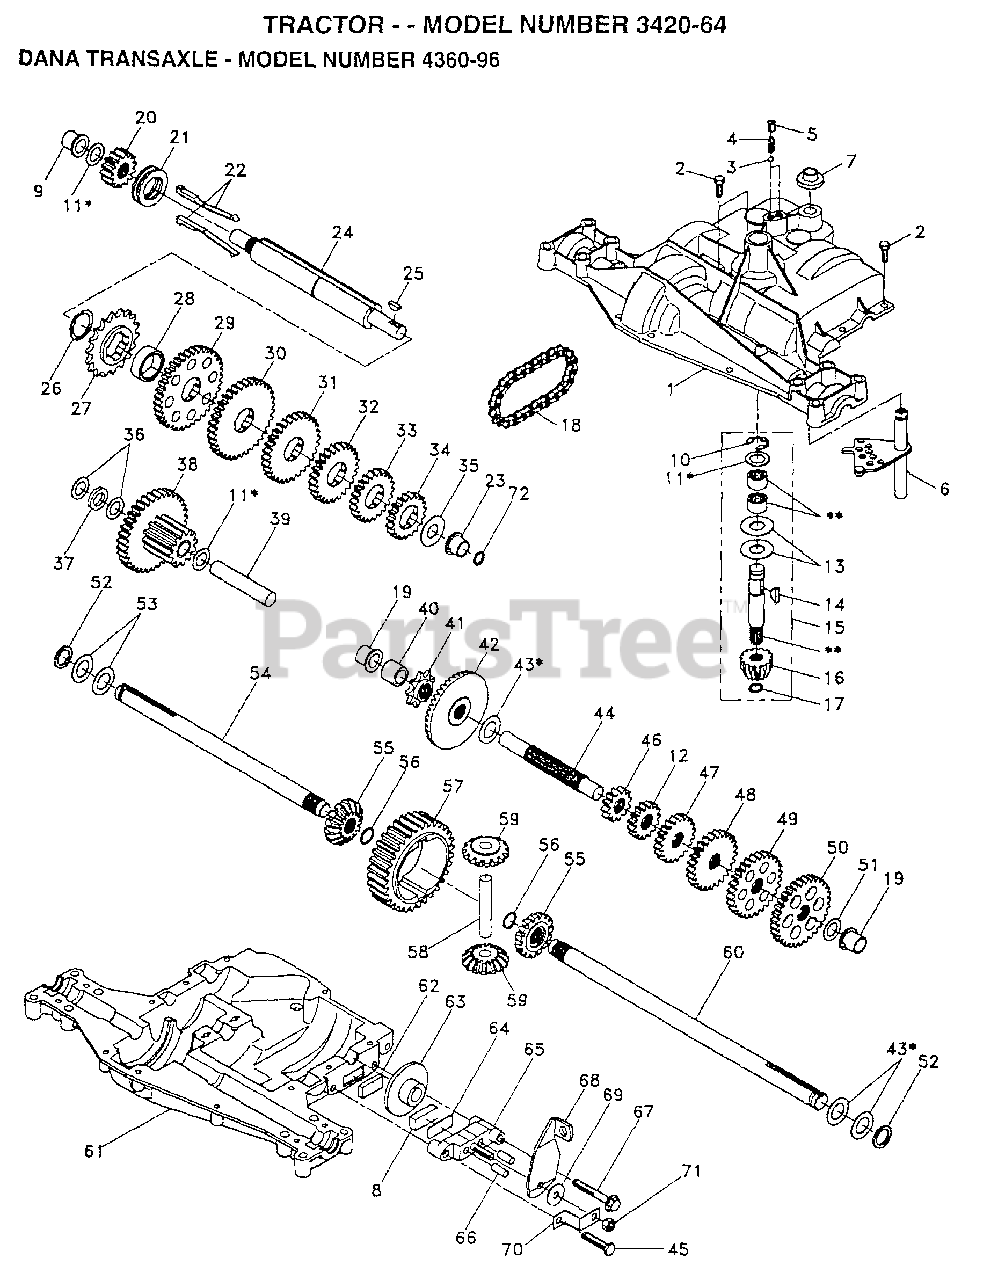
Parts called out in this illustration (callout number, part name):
1	HARNESS.IGNITION
4	"SPRING, DETENT LT"
5	"SCREW, SET LT"
6	KIT SHIFTER ASM
7	SHIFTER BOOT
8	PUCK T
10	RETAINING RING LT
11	ASM KIT SHIM 4689
12	PLUG.PLASTIC
13	WASHER T
14	KEY WOODRUFF-DANA
17	"RING,RETAINING LT"
18	"CHAIN,24 PTCH LT"
19	BEARING.FLNG.5510
20	GEAR SPUR 14 TTH
21	CLUTCH.COL.5467
22	KIT.ASM.CLUTCH KY
23	BEARING.FLNG.5511
24	SHAFT INTERM DANA
25	WOODRUFF KEY
26	"RING,RETAINING LT"
27	SPROCKET 18T T
28	SPACER YT
29	GEAR SPUR 37 TTH
30	GEAR SPUR 35 TTH
31	GEAR SPUR 30T
32	GEAR 25T LT
33	GEAR SPUR 22 TT
34	SPUR GEAR 19T
35	"WASHER, PLAIN LT"
36	WASHER 025
37	SPACER
38	ASSM GEAR COMB
39	SHAFT IDLER
40	SPACER T
41	SPROCKET 9T LT
43	ASM KIT SHIM
44	SHAFT T
45	"SCREW, TAPPING LT"
46	GEAR SPUR 12 TTH
48	"GEAR, SPUR 25T LT"
49	GEAR 28T T
50	"GEAR, SPUR 31T LT"
51	WASHER 060
52	NEOPRENE WASHER
53	WASHER 031
55	GEAR 15T T
56	"RING,RETAINING LT"
58	SHAFT T
59	GEAR 1ST T
61	HOUSING LOWER TNS
62	PUCK T
63	BRAKE DISC. T
64	SPACER LT
66	PIN T
69	WASHER LT
71	NUT.LOCK.5/16-24
72	SEAL.OIL.DAN.5508
